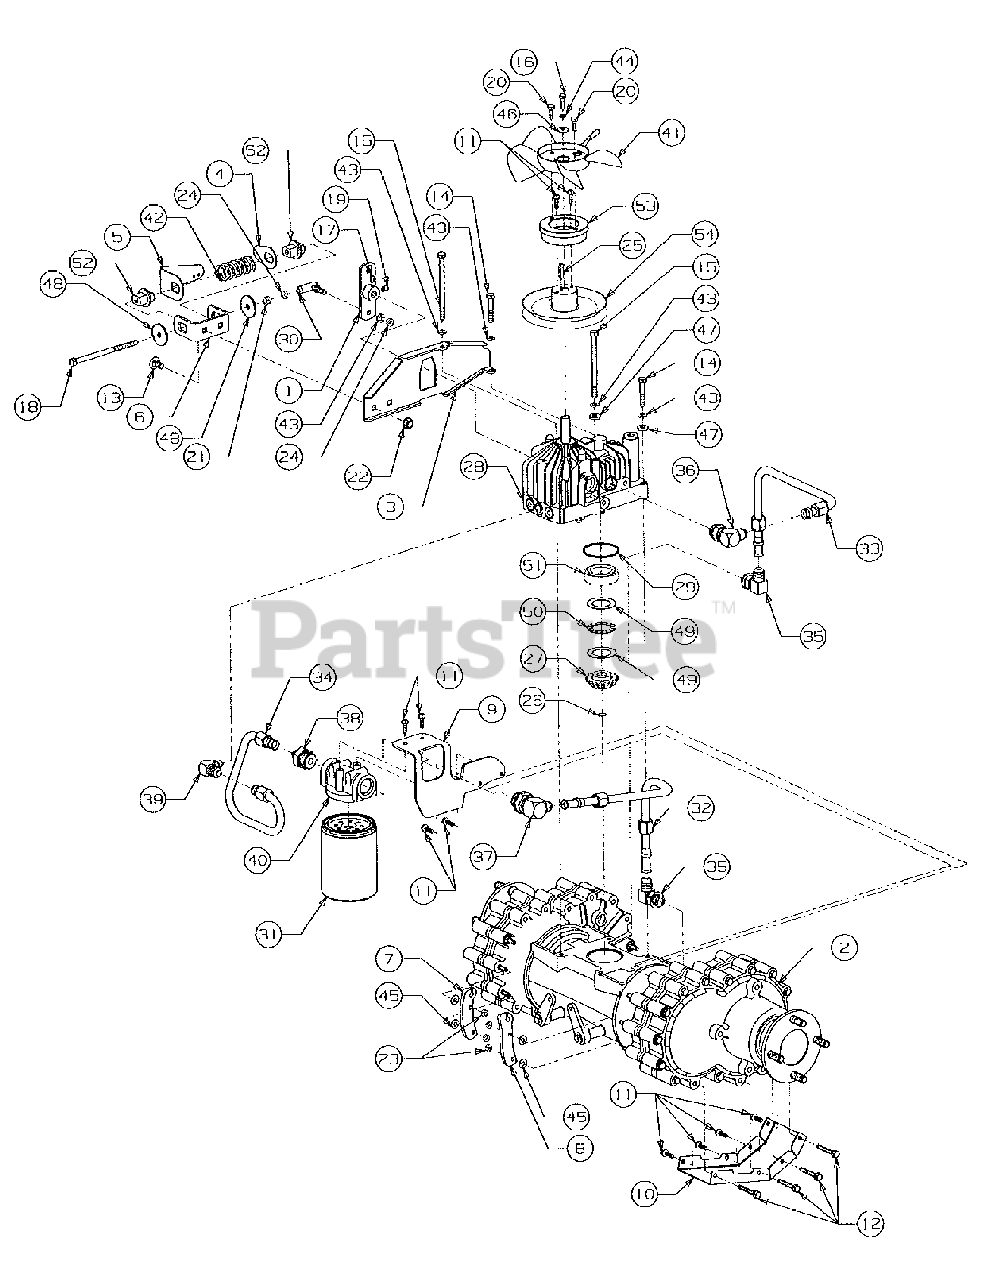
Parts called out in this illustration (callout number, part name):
1	Lever, Forward & Reverse
2	Transmission Assembly, Complete
3	Plate, Neutral Mechanism Mtg
4	Stop, Switch
5	Mount, Switch
6	Bracket, Neutral Mechanism
7	Plate, Left Cable Mtg
8	Plate, Right Cable Mtg
9	Bracket, Oil Filter Mtg
10	Plate, Skid
11	Screw, Hex Wash Hd Tapp, 1/4-20 x .75
12	Screw, Hex Wash Hd Tapp, 1/4-20 x 2.31
13	Bolt, Sht Nk Carriage, 3/8-16 x .75 Gr 5
14	Screw, Hex Cap, 5/16-18 x 1.75 Gr 5
15	Screw, Hex Cap, 5/16-18 x 4.5 Gr 5
16	Screw, Hex Cap, M6-1.0 x 20mm Gr 10.9
17	Set Screw w/ Patch
18	Screw, Hex Cap, 5/16-24 x 5.37 Gr 5
19	Set Screw w/ Patch, 5/16-24 x .38
20	Screw, Hex Cap w/ Patch, 1/4-20 x .75 Gr 5
21	Nut, Hex, 5/16-24
22	Nut, Hex Flanged Lock, 3/8-16
23	Nut, Hex Top Lock, 1/4-20
24	Nut, Hex Jam, 5/16-24 Gr 5
25	Key, Square, 5mm x 5mm x 25mm
26	Ring, Snap, .500 Dia Shaft
27	Gearm Inout Pinion- 20T
28	Pump, Hydrostatic
29	O-Ring, 2.237 ID x .103 Thk
30	Ball Joint
31	Filter, Oil
32	Tube, Filter Inlet
33	Tube, Return
34	Tube, Hydro Inlet
35	Elbow, 90 Deg w/O-Ring
35	O-Ring, 1/2 OD Tube
36	Elbow, 90 Deg w/O-Ring
36	O-Ring, 5/8 OD Tube
37	Elbow, 90 Deg w/O-Ring
37	O-Ring, 3/4 OD Tube
38	Connector, Straight w/O-Ring
38	O-Ring, 3/4 OD Tube
39	Elbow, 90 Deg w/O-Ring
39	O-Ring, 1/4 OD Tube
40	Head, Filter
41	Fan, Hydro 8''
42	Spring, Compression, 1.20 OD x 2.70
43	Washer, Lock, 5/16
44	Washer, Lock, 1/4
45	Washer, Flat, .25 x .62 x .0515 Thk
46	Washer, Flat, .25 x .750 x .119 Thk
47	Washer, Flat, .312 x .750 x .119 Thk
48	Washer, Flat, .206 x .448 x .105 Thk
49	Washer, Thrust, 1.25 x 1.937 x .031 Thk
50	Bearing, Thrust, 1.25 x 1.937 x .0781 Thk
51	Spacer, Input Pinion
52	Guide, Neutral Stop
53	Hub, Fan Mtg
54	Pulley, Transmission Drive
